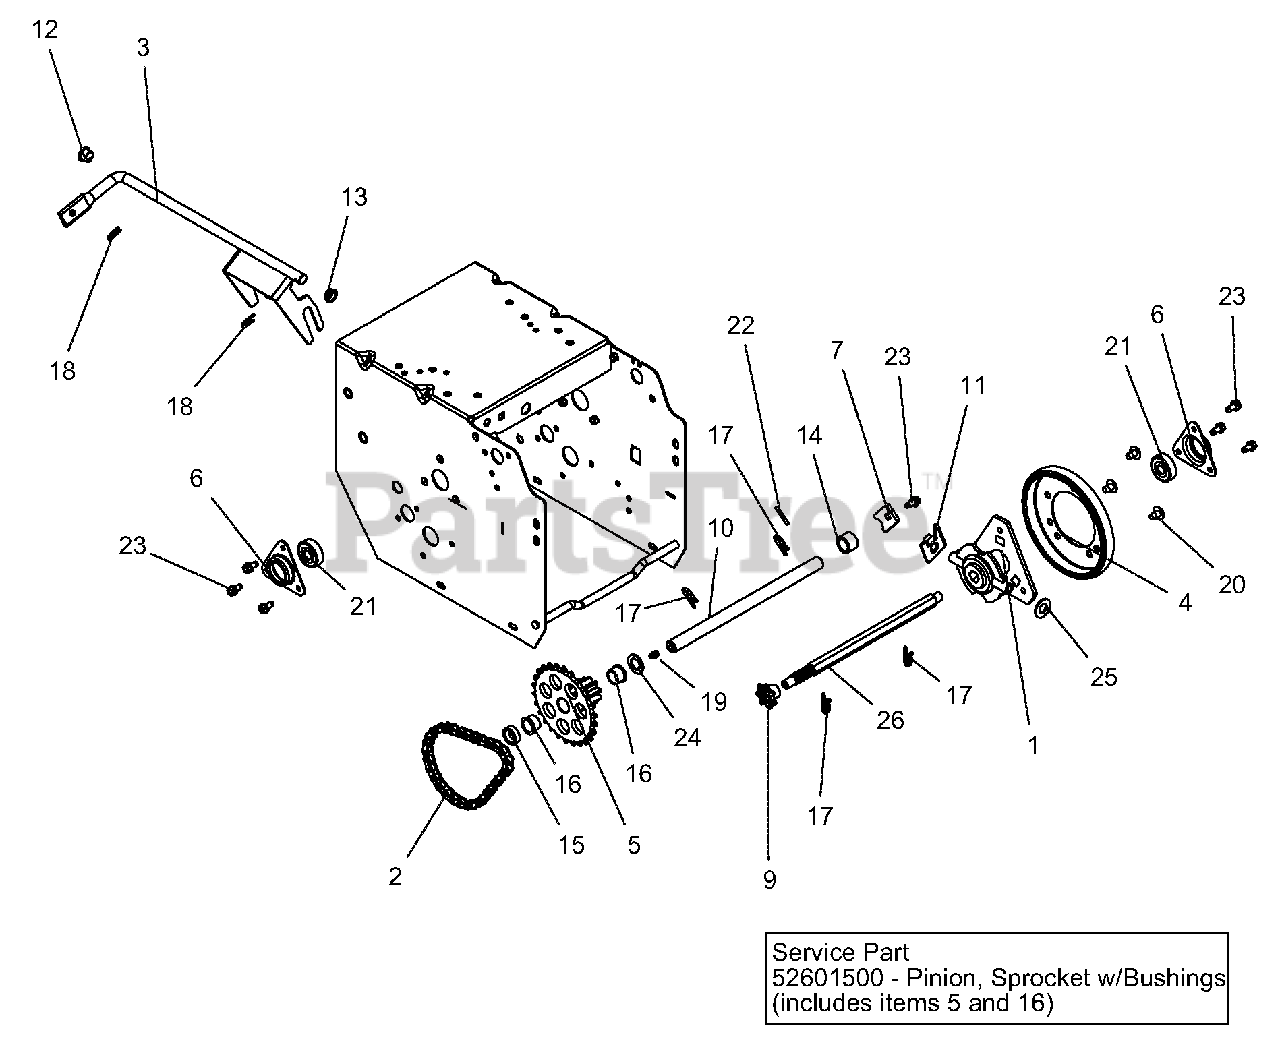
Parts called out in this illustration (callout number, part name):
1	CARRIER, DRIVE DISK
2	CHAIN - #41, 32 PITCHES
3	WELDMENT, SHIFT FORK
4	FRICTION, DISC
5	PINION & SPROCKET
6	FLANGE, BEARING
7	TAB, ANTI ROTATION
9	SPROCKET, PINION 7T W/SPLINE
10	SHAFT, PINION TRACK
11	BRACKET, FORMED - SHIFT FORK
12	BUSHING, POLYLINER-.50 SPLIT
13	BUSHING, POLYLINER-.50 SNAPIN
14	SPACER, .635X.880X.611
15	BSHG-SLV, .635X.880X.305
16	BSHG-FLG .625X.750X.500X.875
17	PIN, SPRING CLIP
18	CLIP, SPRING
19	ZERK,FITTING .25X.125 DRIVE IN
20	SCR-TAP SERRDHDTX .31-18X.50BP
21	BRG-BALL .437X1.375X.437
22	@PIN-GRV .125X1.00 TP E ALLOY
23	SCR-TAP .25-20X.50 HWH TR YWZ
24	WSHR-FL-STL .630X1.005X.062 YZ
25	WSHR-FL-STL .505X1.00X.062YWZC
26	SHAFT, HEX W/SPLINE TRACK
